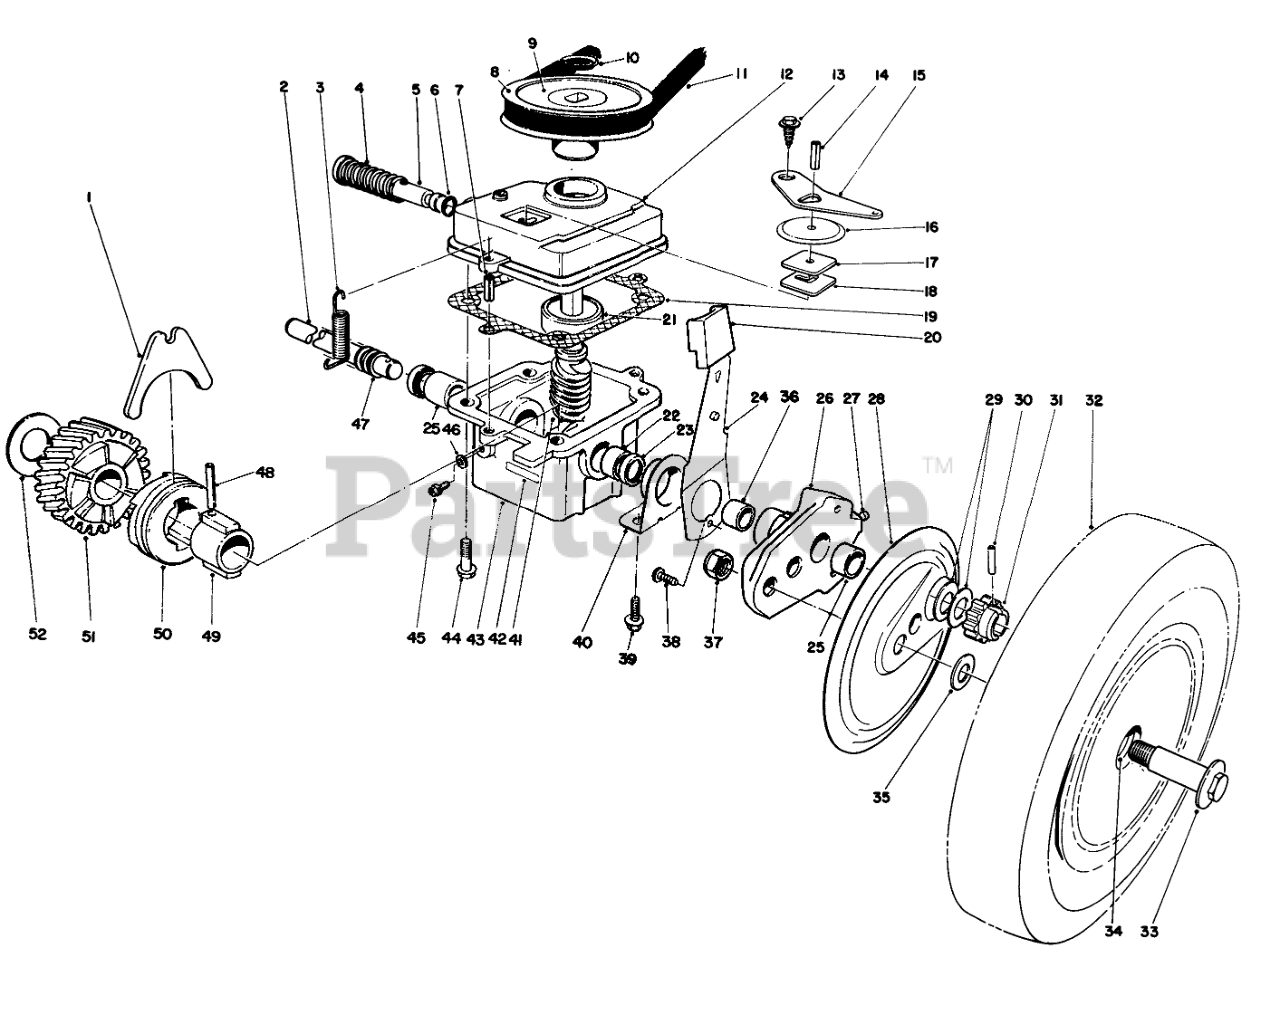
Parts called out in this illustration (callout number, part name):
1	SHIFTER FORK
2	DRIVE SHAFT
3	TENSION SPRING
4	SPRING
5	SHIFTER ROD
6	O-RING
7	3/16 X 1/2 ROLL PIN
8	PULLEY
9	DECAL
10	PUSH-ON 93-3236
11	V BELT
12	GEAR CASE COVER
13	Screw
14	SPIROL PIN H D
15	SHIFTER ARM
16	DUST COVER
17	DUST FILTER
18	LATCH PLATE
19	GASKET
20	KNOB-ARM
21	BEARING
22	BUSHING
23	SEAL-OIL
24	SPRING ARM ASSY-FRONT
25	BUSHING
26	Arm-Pivot (Incl. Ref. #25, 27 & 36)
27	FITTING-GREASE
28	WHEEL COVER
29	THRUST WASHER
30	Pin
31	PINION GEAR 15T
32	Wheel, Tire & Gear Assy (Incl. Ref. #34)
33	BOLT-WHEEL
34	BUSHING
35	WASHER
36	BUSHING
37	Nut
38	SCREW
39	SCREW-HWHTF
40	END CAP
41	Worm Shaft & Gear (Incl. Ref. #51)
42	DECAL
43	Gear Case (Incl. Ref. #22, 23 & 25)
44	Screw
45	NYLON SCREW
46	FILL PLUG GASKET
47	COVER-SHAFT, DRIVE
48	COIL PIN
49	SLEEVE
50	CLUTCH JAW
51	Gear-Helical
52	THRUST WASHER
